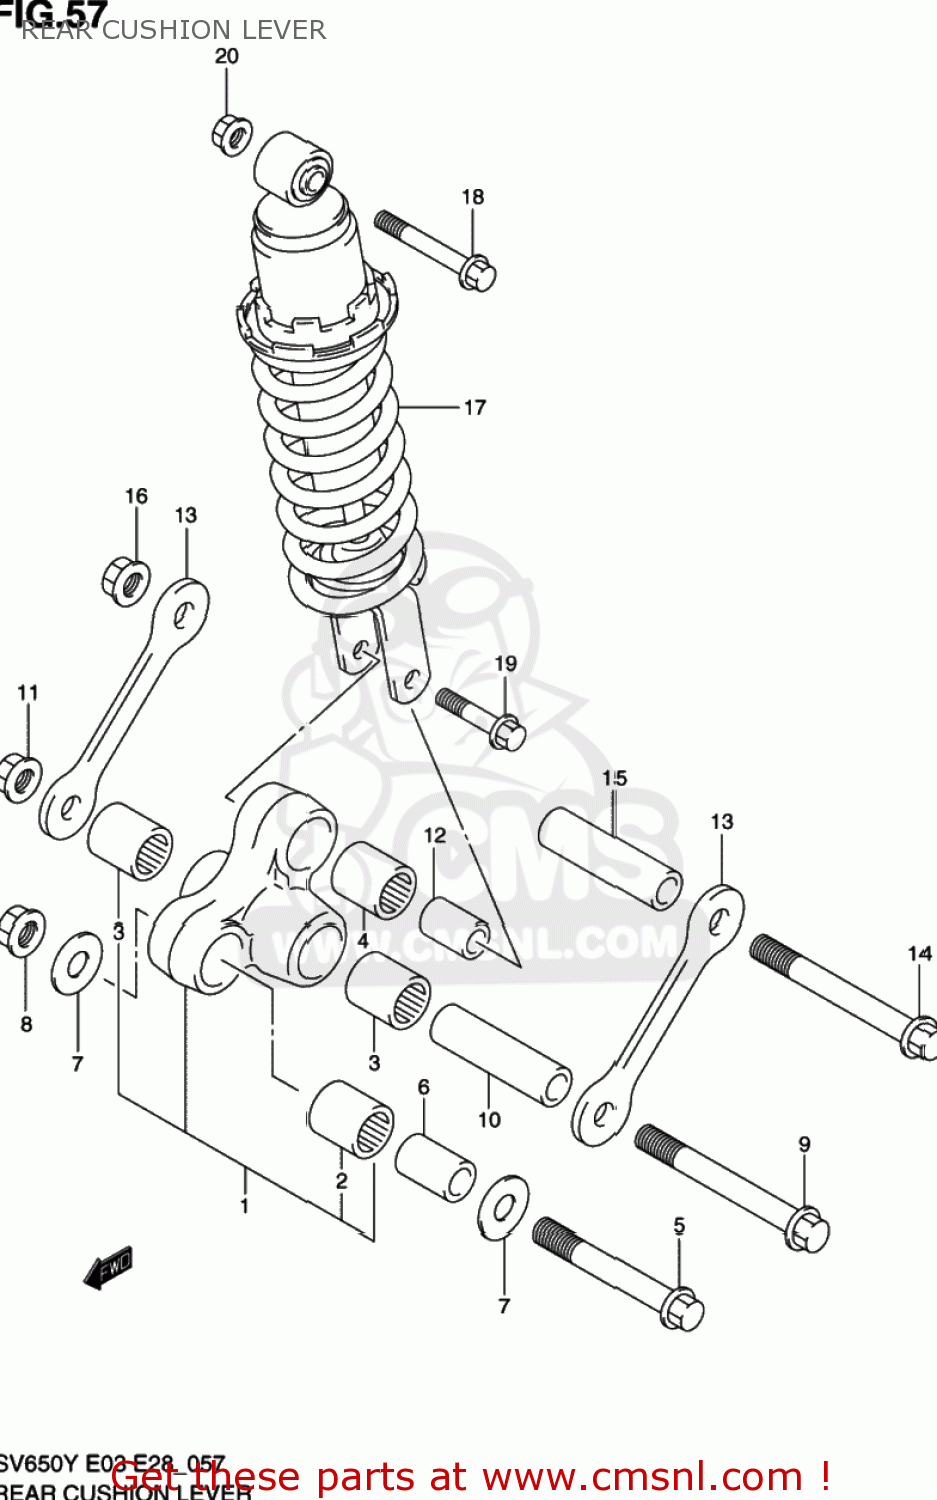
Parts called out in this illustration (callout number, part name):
1	LEVER SET,RR CUSHION
2	BEARING(20X27X30)
3	BEARING(20X27X23.5)
4	BEARING(17X24X26)
5	BOLT,RR CUSHION LEVER FR
6	SPACER,RR CUSHION LEVER FR
7	WASHER(12X34X1)
8	NUT 12MM
9	BOLT(12X96)
10	SPACER,RR CUSHION LEVER CTR
11	NUT 12MM
12	SPACER,RR CUSHION LEVER
13	ROD,RR CUSHION
14	BOLT(12X96)
15	SPACER,RR CUSHION LEVER CTR
16	NUT 12MM
17	ABSORBER ASSY,RR SHOCK
18	BOLT(10X70)
19	BOLT(10X48)
20	NUT
